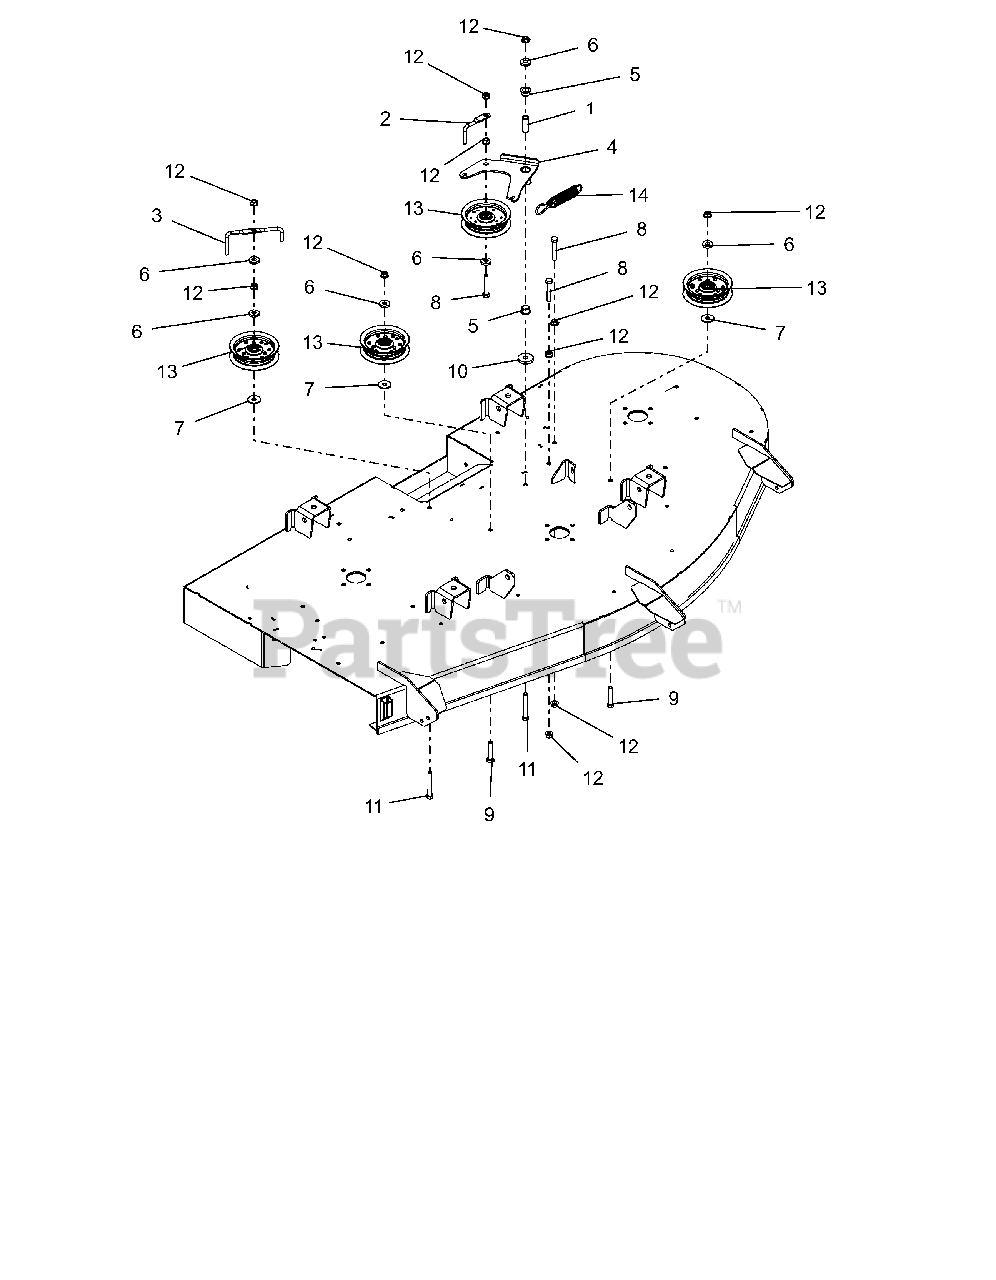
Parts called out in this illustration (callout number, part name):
1	SPACER, .375IDX.625ODX1.66 PM
2	WIREFORM, BELT FINGER
3	WIREFORM, BELT FINGER
4	WLDMT, IDLER ARM-42"
5	BSHG-FLG, .625X.750X.500X1.00
6	WSHR, FLT .406X1.00X.188 ZCC
7	WSHR FL STL .406X1.25X.10ZC120
8	BLT,HEX .38-16X2.25 G5 ZCC
9	BLT,HEX .38-16X2.00 G5 ZCC
10	WSHR, FLT .406X1.50X.245 ZCC
11	BLT, HEX .38-16X2.75 G5 ZCC
12	NUT-LK-TOP-FLG .38-16 ZC120
13	ASM, IDLER 4"
14	SG-TENS .135X.98X6.0 WLD 62
